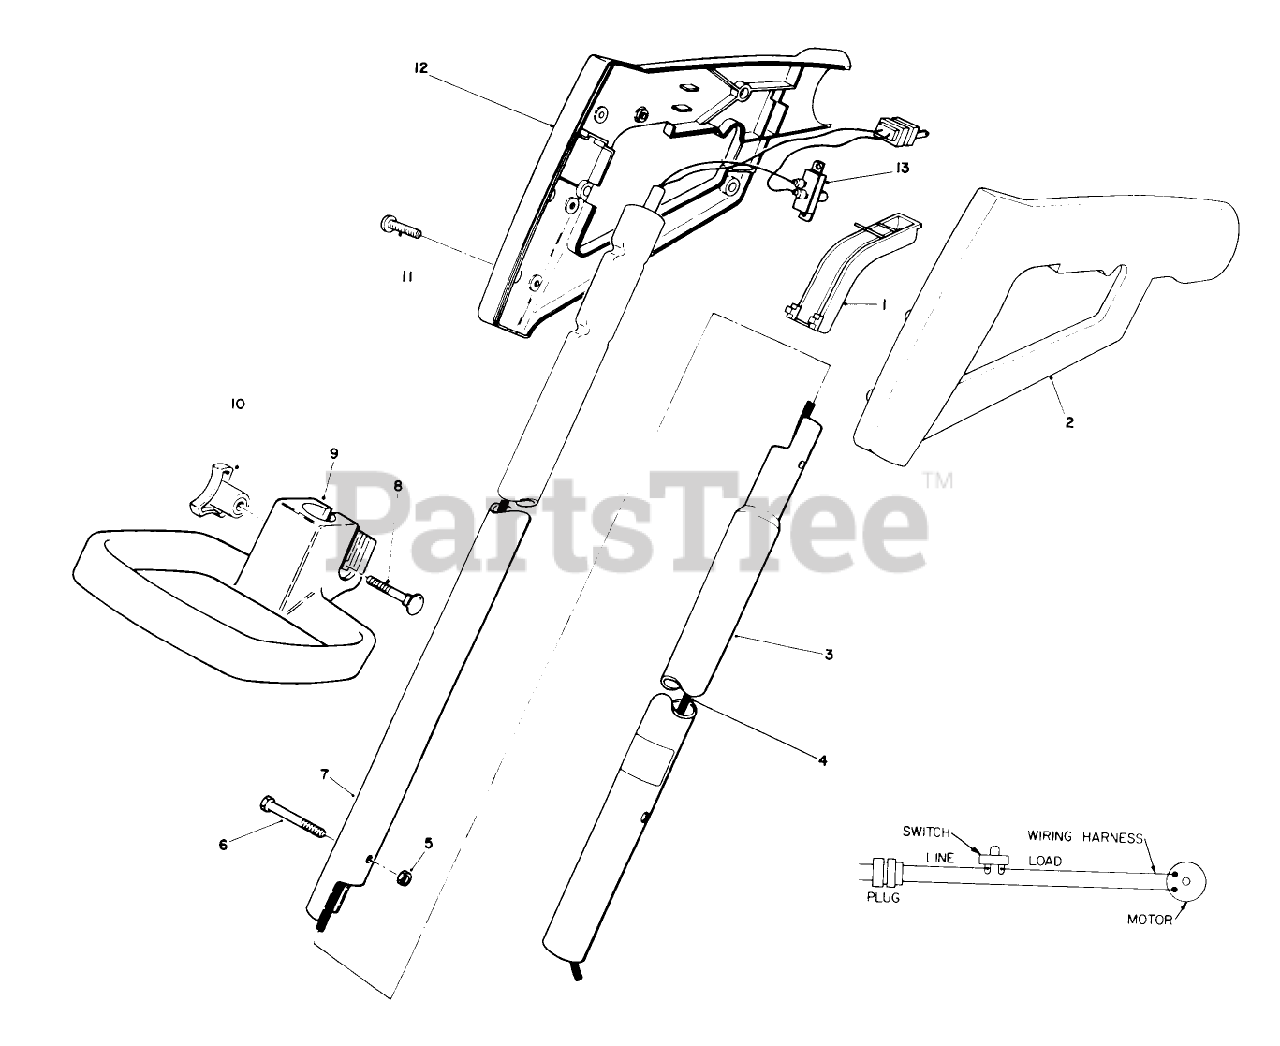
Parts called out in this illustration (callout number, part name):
1	TRIMMER - SWITCH BAR
2	HANDLE GRIP, LH
3	TUBE-LOWER EXTENSION
4	1010 WIRE HARNESS
5	NUT-LOCK, NI
6	HEX HD MACHINE SCREW
7	UPPER TUBE
8	BOLT-CARR
9	Handle-Adjust
10	HANDLE KNOB
11	Screw
12	HANDLE GRIP, RH
13	SWITCH
